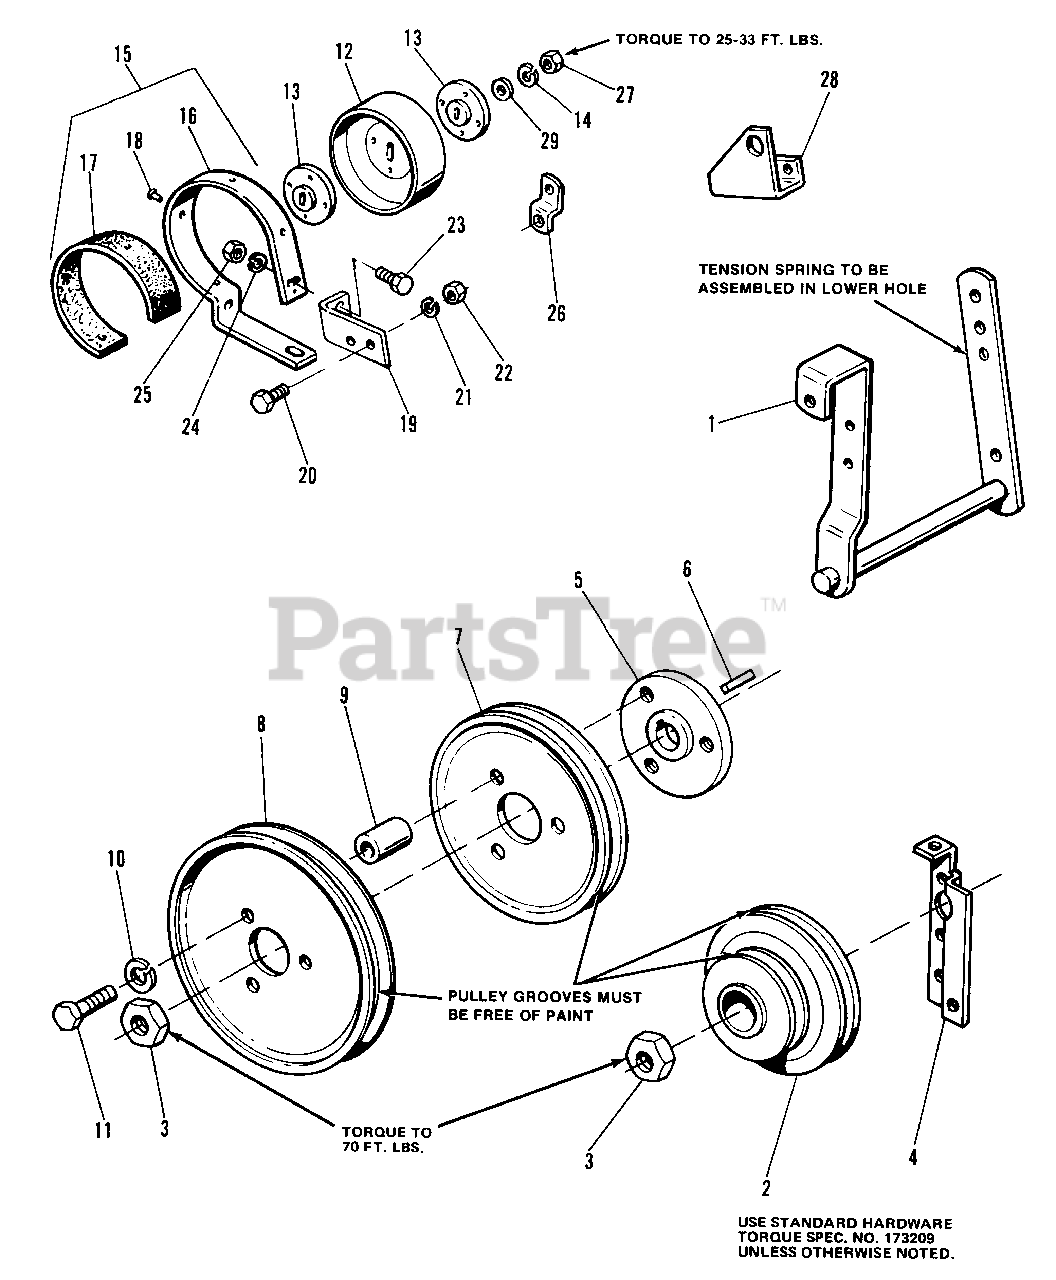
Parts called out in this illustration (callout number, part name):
1	PIVOT LEVER ASSEMBLY
2	FRONT PULLEY ASSEMBLY
3	LOCKNUT, Jam, 3/4-16
4	SUPPORT, Belt Retainer
5	HUB, Pulley
6	KEY, Woodruff, No. 9
10	LOCKWASHER, 5/16
11	CAPSCREW, Hex Hd., 5/16-18 x 2
12	DRUM, Brake
13	WASHER, Special
14	LOCKWASHER, 7/16
15	BRAKE BAND ASSEMBLY
16	BAND, Brake
17	LINING, Brake
18	RIVET, Tubular
19	BRACKET, Brake Band
20	CAPSCREW, Hex Hd., 3/8-16 x 1-1/4
21	LOCKWASHER, 3/8
22	NUT, Hex Full, 3/8-16
23	CAPSCREW, Hex Hd., 1/4-20 x 3/4
24	LOCKWASHER, 1/4
25	NUT, Hex Full, 1/4-20
26	CLIP, Spring
27	NUT, Hex Full, 7/16-14
28	BEARING, Idler Pivot
29	WASHER, 3/8
